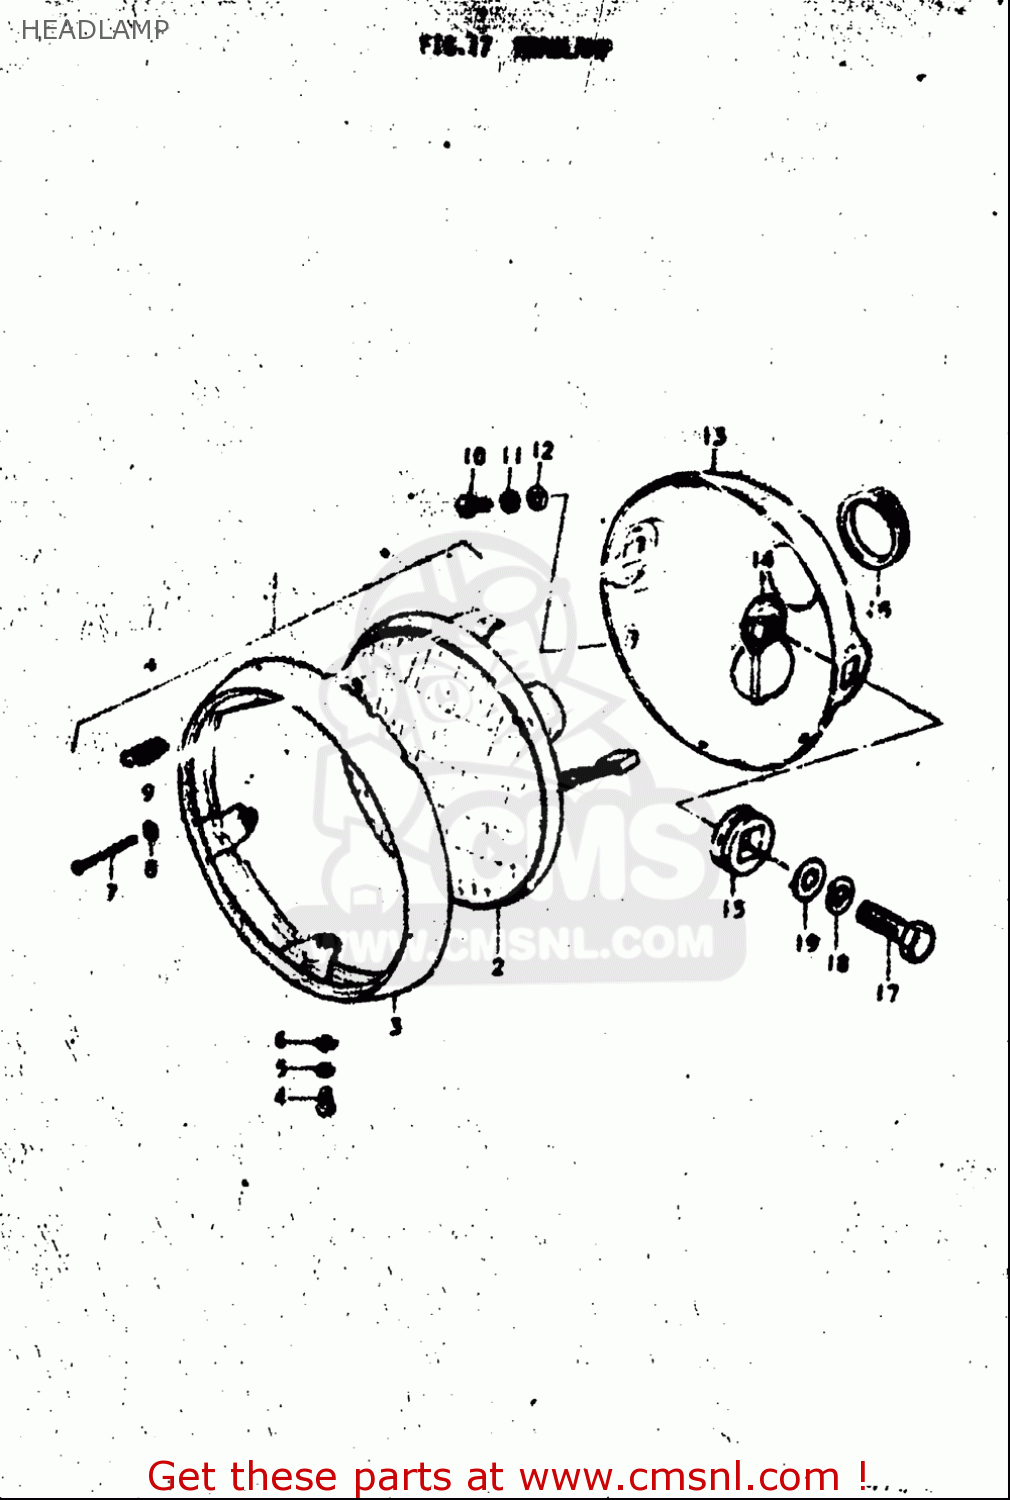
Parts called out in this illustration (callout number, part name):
4	SCREW,HEAD LAMP RIM
6	NUT
7	SCREW,HEADLAMP ADJUST
8	NUT,HEADLAMP ADJUSTER
10	SCREW
11	WASHER,LOCK
12	WASHER
13	HOUSING,HEADLAMP
15	CUSHION,HEADLAMP HOUSING
17	BOLT
18	WASHER,LOCK
19	WASHER
